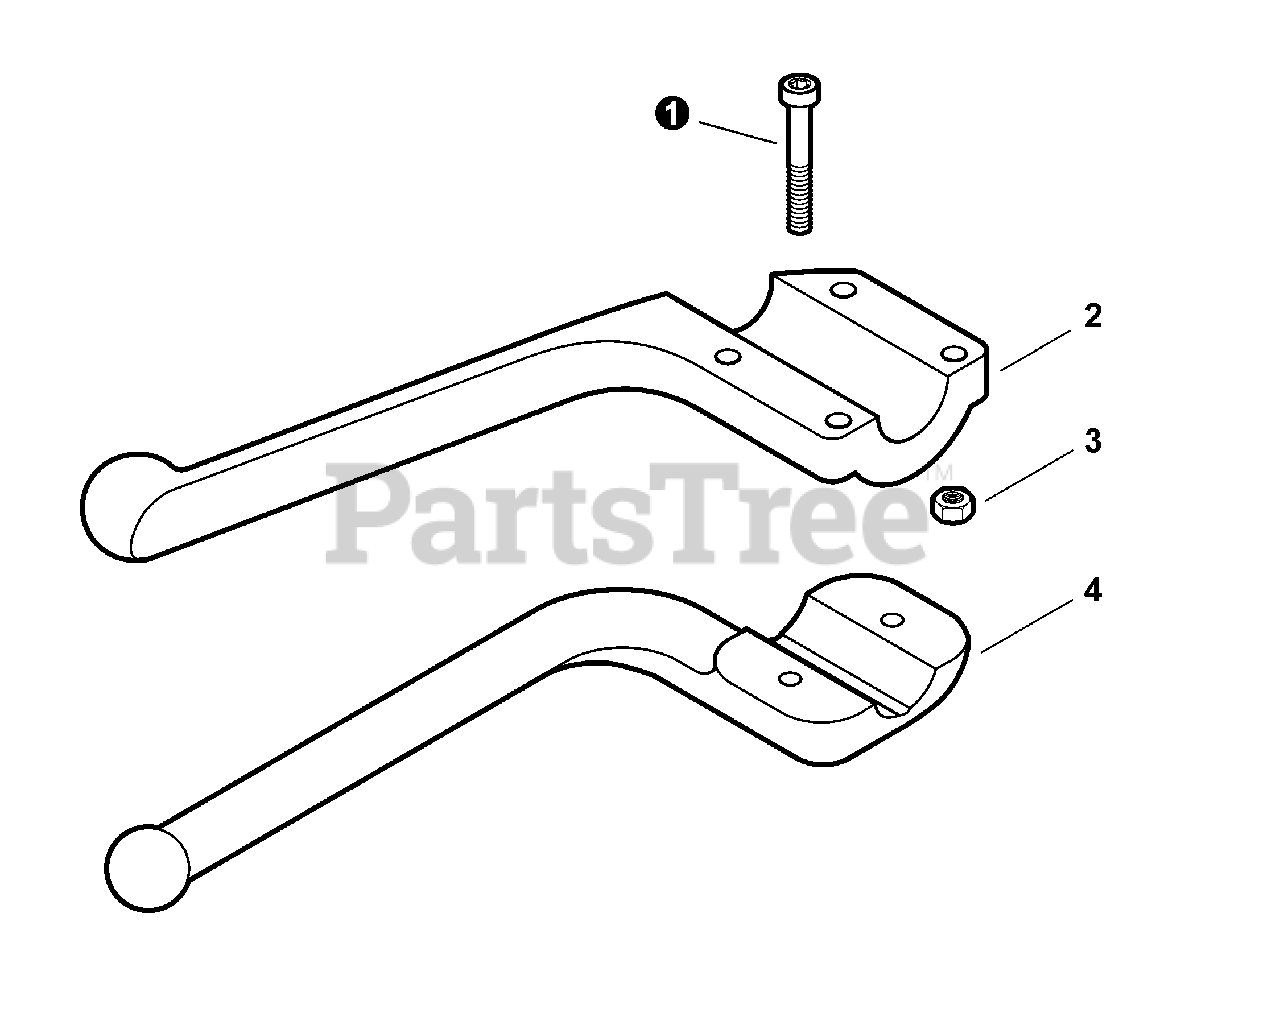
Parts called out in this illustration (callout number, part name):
1	BOLT, TORX 5×35
2	BAR, BARRIER
3	NUT M5
4	BAR, BARRIER
